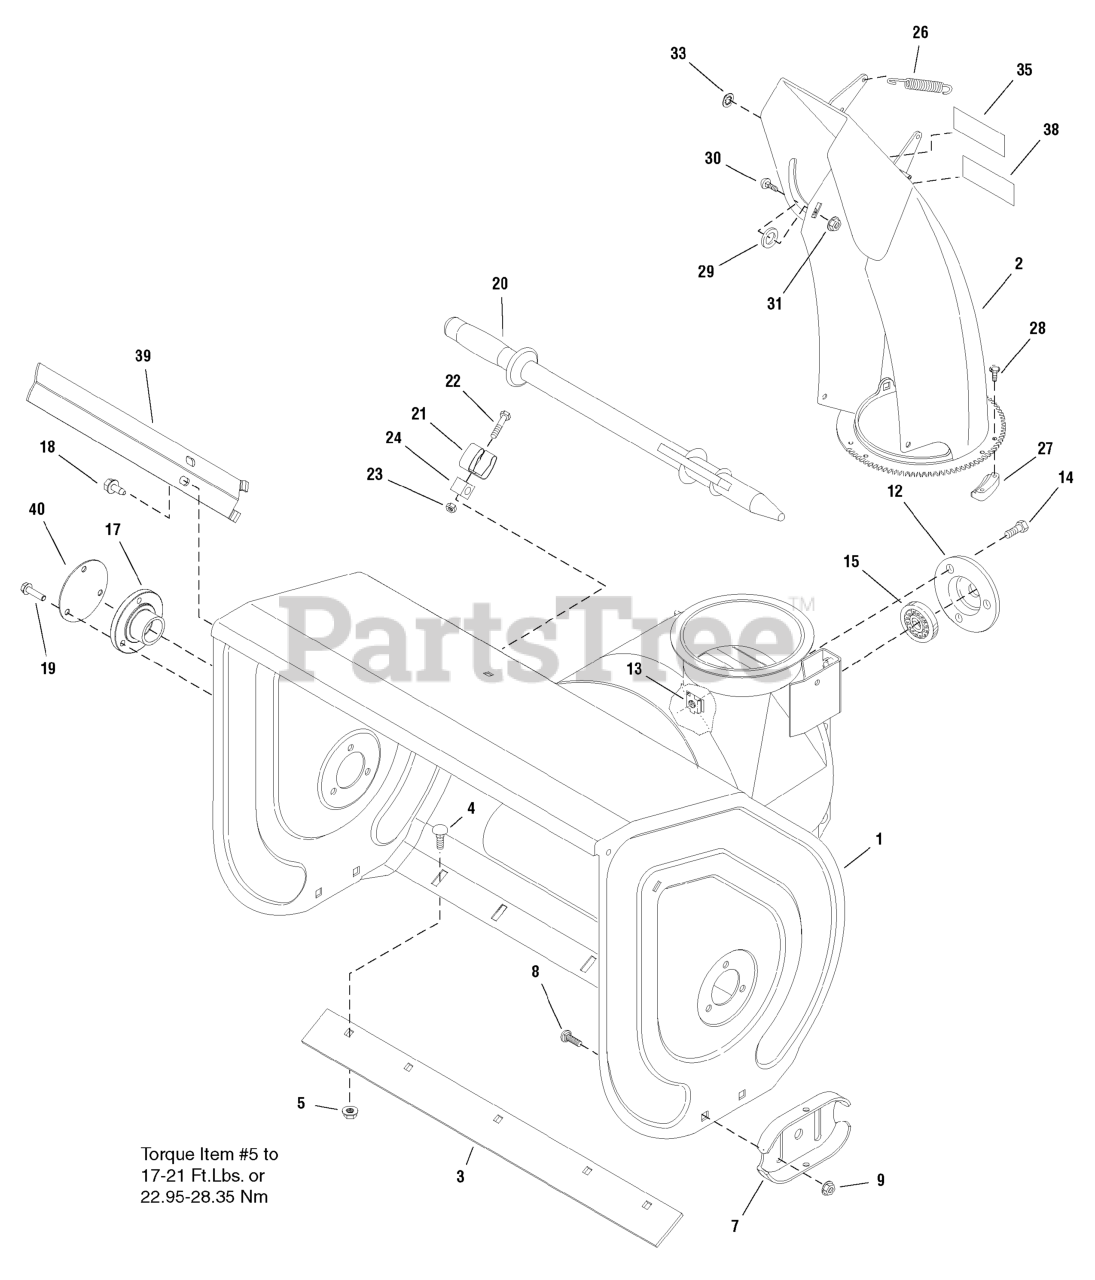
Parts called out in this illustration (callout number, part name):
1	AUGER HOUSING ASSEMBLY, 28" Auger
1	AUGER HOUSING ASSEMBLY, 30" Auger
1	AUGER HOUSING ASSEMBLY, 32" Auger
2	CHUTE & DEFLECTOR ASSEMBLY
3	BLADE, Scraper, 28"
3	BLADE, Scraper, 30"
3	BLADE, Scraper, 32"
4	CARRIAGE BOLT, 5/16-18 x 5/8 G5
5	NUT, Hex Flange Two-Way Lock, 5/16-18
7	SKID, Shoe Reversible
8	CARRIAGE BOLT, 3/8-16 x 3/4 G5
9	NUT, Hex Flange ESNA, 3/8-16
12	BEARING, Retainer
13	RETAINER, Nut, 5/16-18
14	SCREW, Hex Whiz Lock Flange, 5/16-18 x 3/4
15	BEARING, Greased
17	BUSHING, Auger Flange
18	SCREW, Hex Washer Head Taptite 5/16-18 x 3/4
19	SCREW, Hex Washer Head Taptite 5/16-18 x 1-1/4
20	STICK, Cleanout w/Brush
21	CLIP, Retainer
22	SCREW, Hex Washer Head Slot
23	NUT, Hex Lock 10-24 w/Nylon Insert
24	BLOCK, Universal Pivot
26	SPRING, Extension
27	RETAINER, SPOUT
28	CAPSCREW, Hex Washer Head Taptite, #10C x 5/8 GR5 BZ
29	WASHER, Nylon, .388 x 1.12 x .030
30	CARRIAGE BOLT, 5/16-18 x 3/4 G5
31	NUT, Hex Flange ESNA, 5/16-18
33	NUT, Push for .312 DIA Stud Capped .625OD
35	DECAL, Hinge Upper
38	DECAL, Hinge Lower
39	CUTTER, Drift
40	COVER, Bushing
